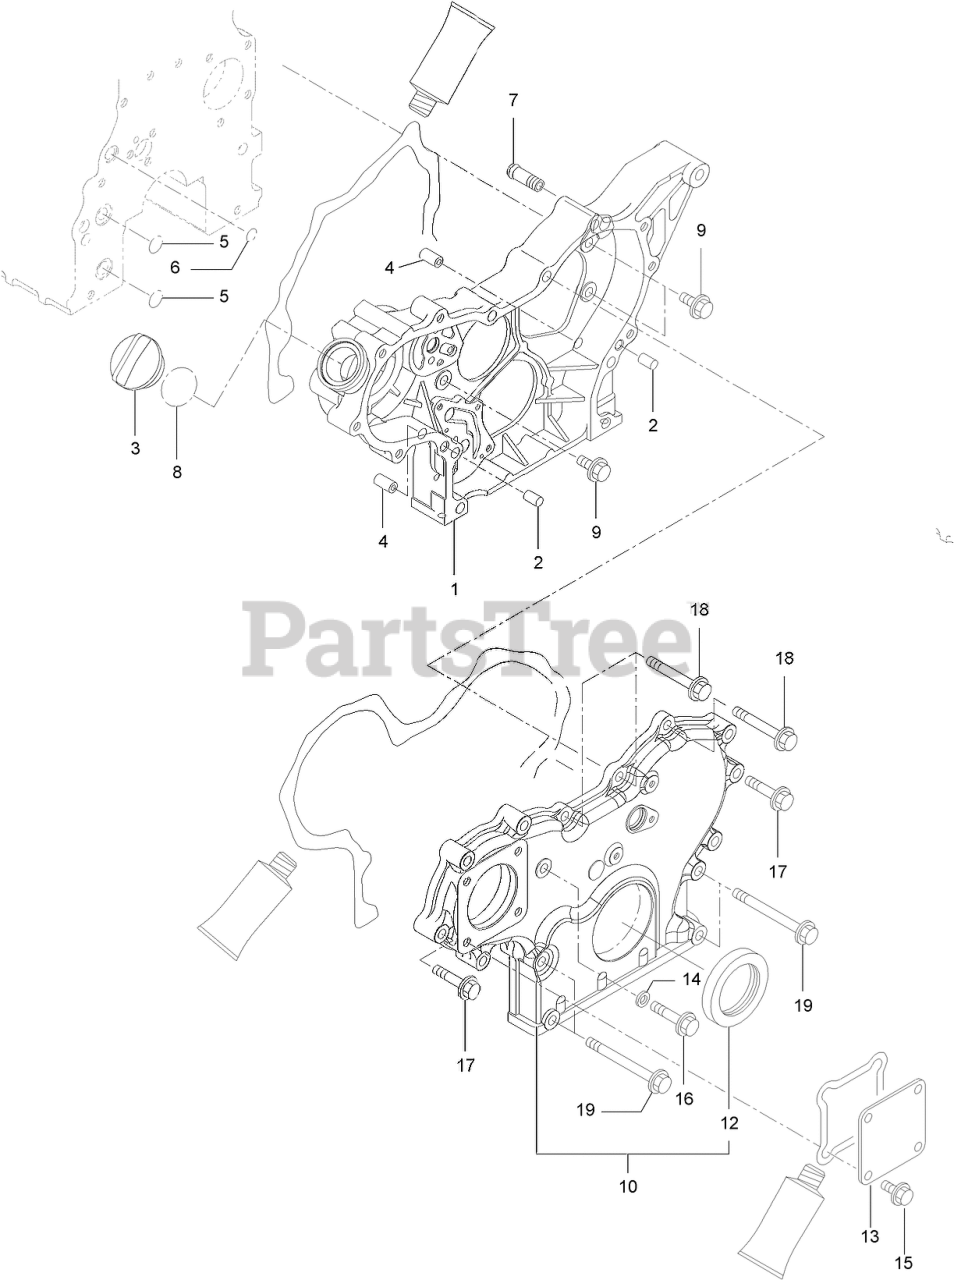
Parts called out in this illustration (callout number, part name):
1	CASE-GEAR
3	COVER-FILLER
10	GEARCASE COVER ASM
12	SEAL-OIL
14	WASHER-SEAL
